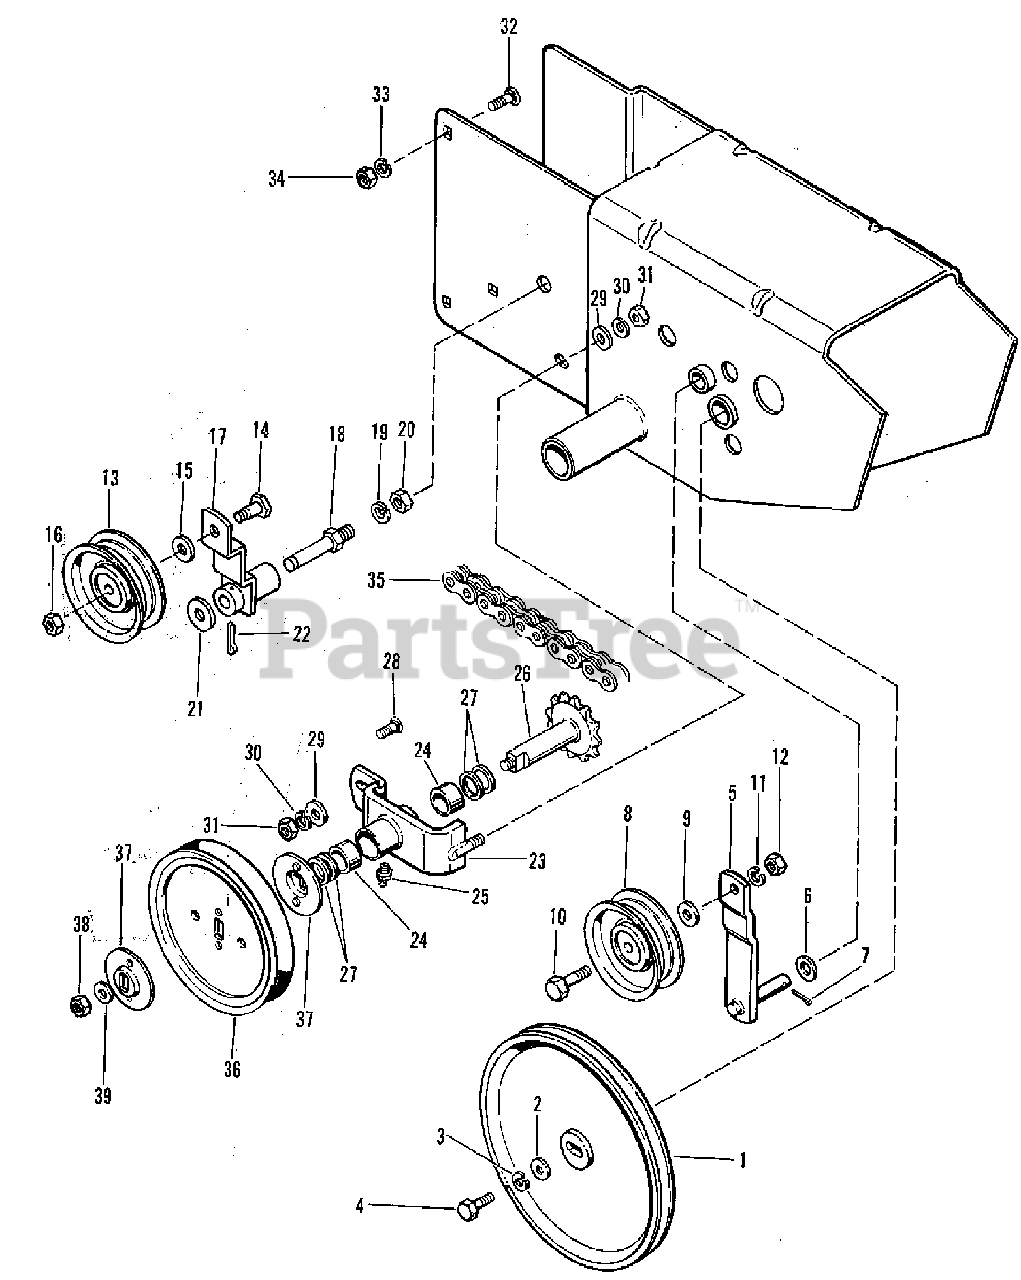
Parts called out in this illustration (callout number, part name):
1	PULLEY, Transmission
2	WASHER, 5/16
3	LOCK WASHER, 5/16
4	CAPSCREW, Hex Head, 5/16-18 x 7/8
5	IDLER ARM ASSEMBLY
6	WASHER, 3/8
7	COTTER PIN
8	PULLEY, Idler
9	WASHER, 5/16
10	CAPSCREW, Hex Head, 3/8-16 x 1-1/4
11	LOCK WASHER,3/8
12	NUT, Hex, 3/8-16
13	PULLEY, Idler
14	SCREW, Special
15	WASHER, 5/16
16	NUT, Hex Jam, 3/8-16
17	LEVER ASSEMBLY
19	WASHER, 7/16
20	NUT, Hex Jam, 7/16
21	WASHER, 3/8
22	COTTER PIN
23	BEARING HOUSING ASSEMBLY
25	GREASE FITTING
26	SPROCKET & SHAFT ASSEMBLY
27	SPACER WASHER
28	CARRIAGE BOLT, 3/8-16 x 1
29	WASHER, 5/16
30	LOCKWASHER, 3/8
31	NUT, Hex, 3/8-16
32	CARRIAGE BOLT, 3/8-16 x 3/4
33	LOCKWASHER, 3/8
34	NUT, Hex, 3/8-16
35	CHAIN, W/Connecting Link
37	WASHER, Special
38	NUT, Hex Jam, 3/8-16
39	WASHER, 3/8
